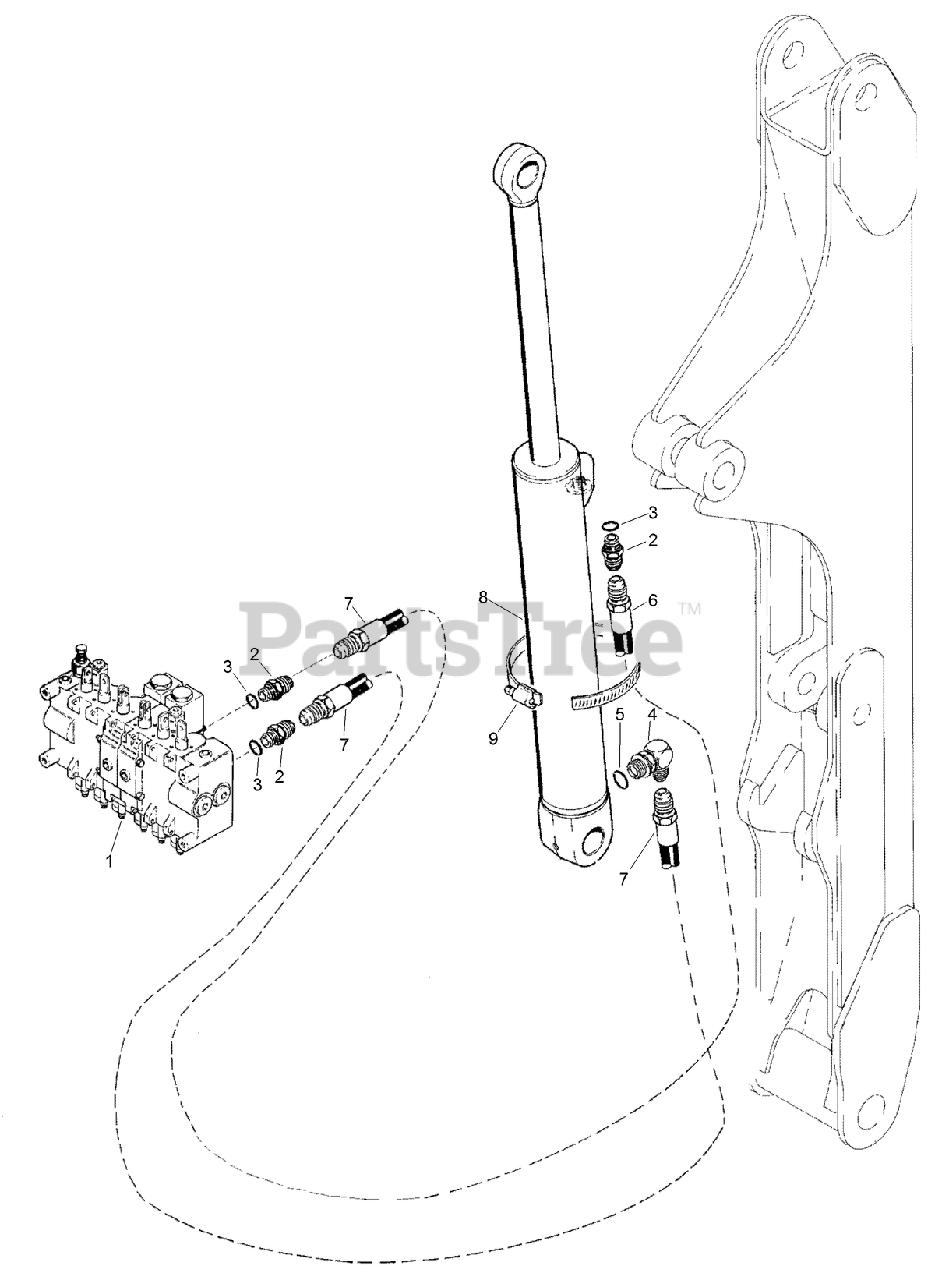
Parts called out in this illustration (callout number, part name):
1	HYD CONTROL VALVE ASM
2	CONNECTOR-Str Thd 1/2, 37FL-ORB 1/2
3	O-RING
4	ELBOW-90 DEG
5	O-RING
6	HOSE-To Rod End Of Dipper Cylinder
7	HOSE-To Closed End of Dipper Cylinder
8	CYLINDER-76 (3) ID x 498 mm (19-5/8 inch) Stroke, Dipper
9	CLAMP-Hose Type F #60
